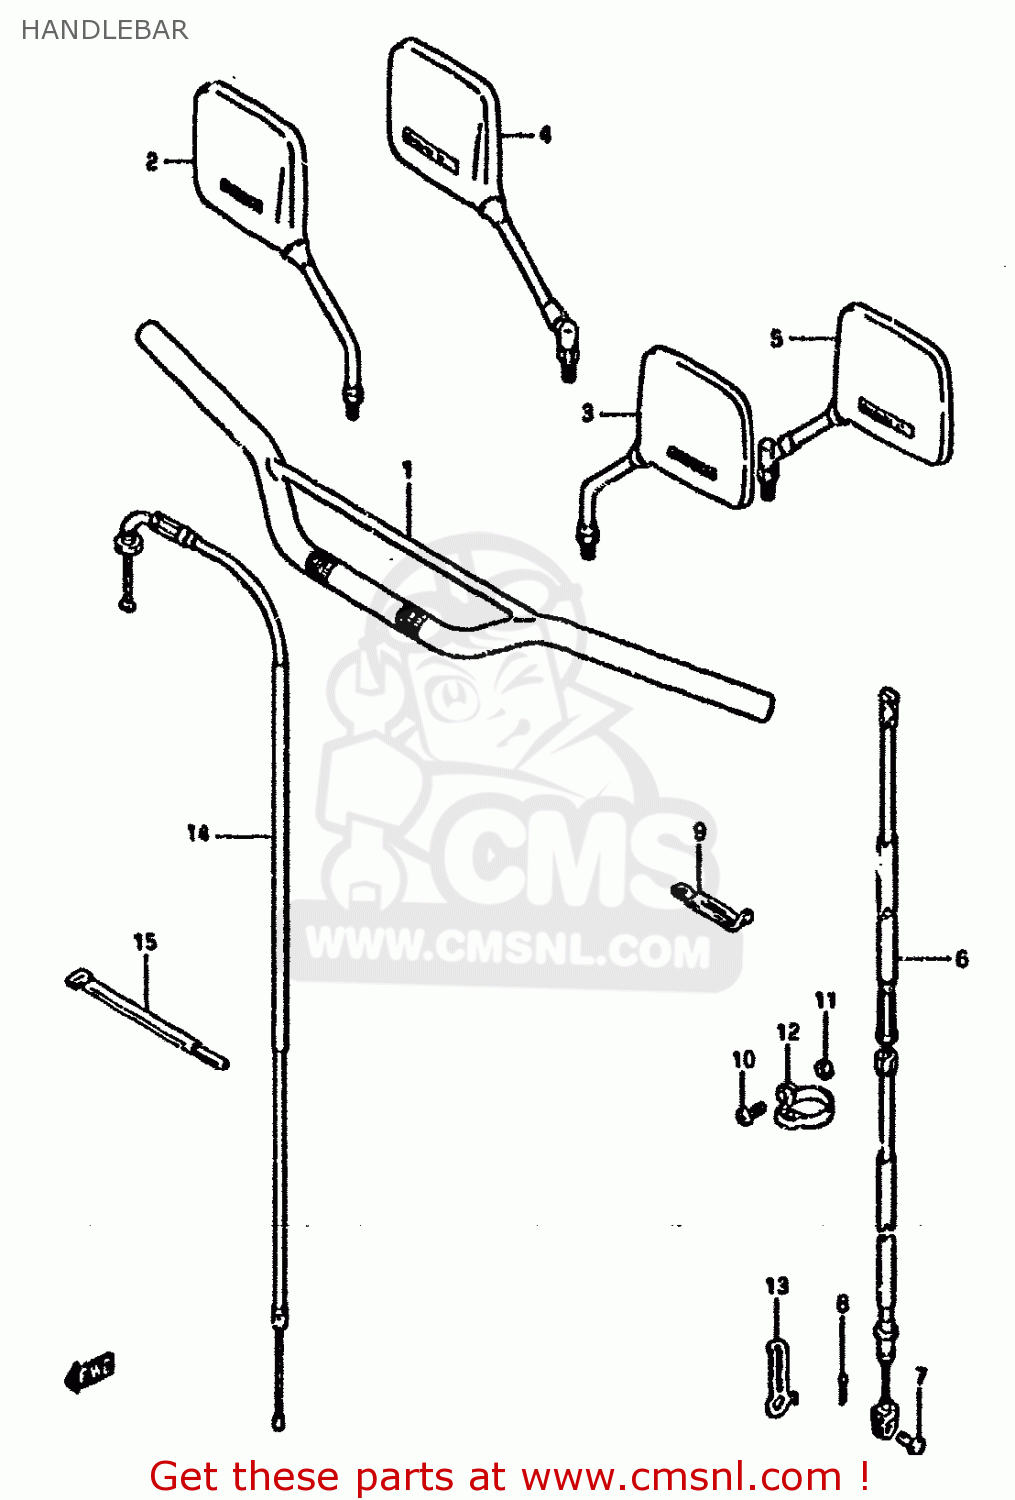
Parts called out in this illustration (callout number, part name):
1	HANDLEBAR
2	MIRROR, REAR VIEW RH
3	MIRROR ASSEMBLY,LEFT
4	MIRROR ASSY, REAR VIEW RH
5	MIRROR ASSY, REAR VIEW LH
6	CABLE ASSY,CLUTCH
7	PIN(L:15)
8	PIN
9	CLAMP
10	SCREW
11	NUT 5MM
12	CLAMP,CABLE
13	CLAMP,CABLE
14	CABLE ASSY,THROTTLE
15	CLAMP
